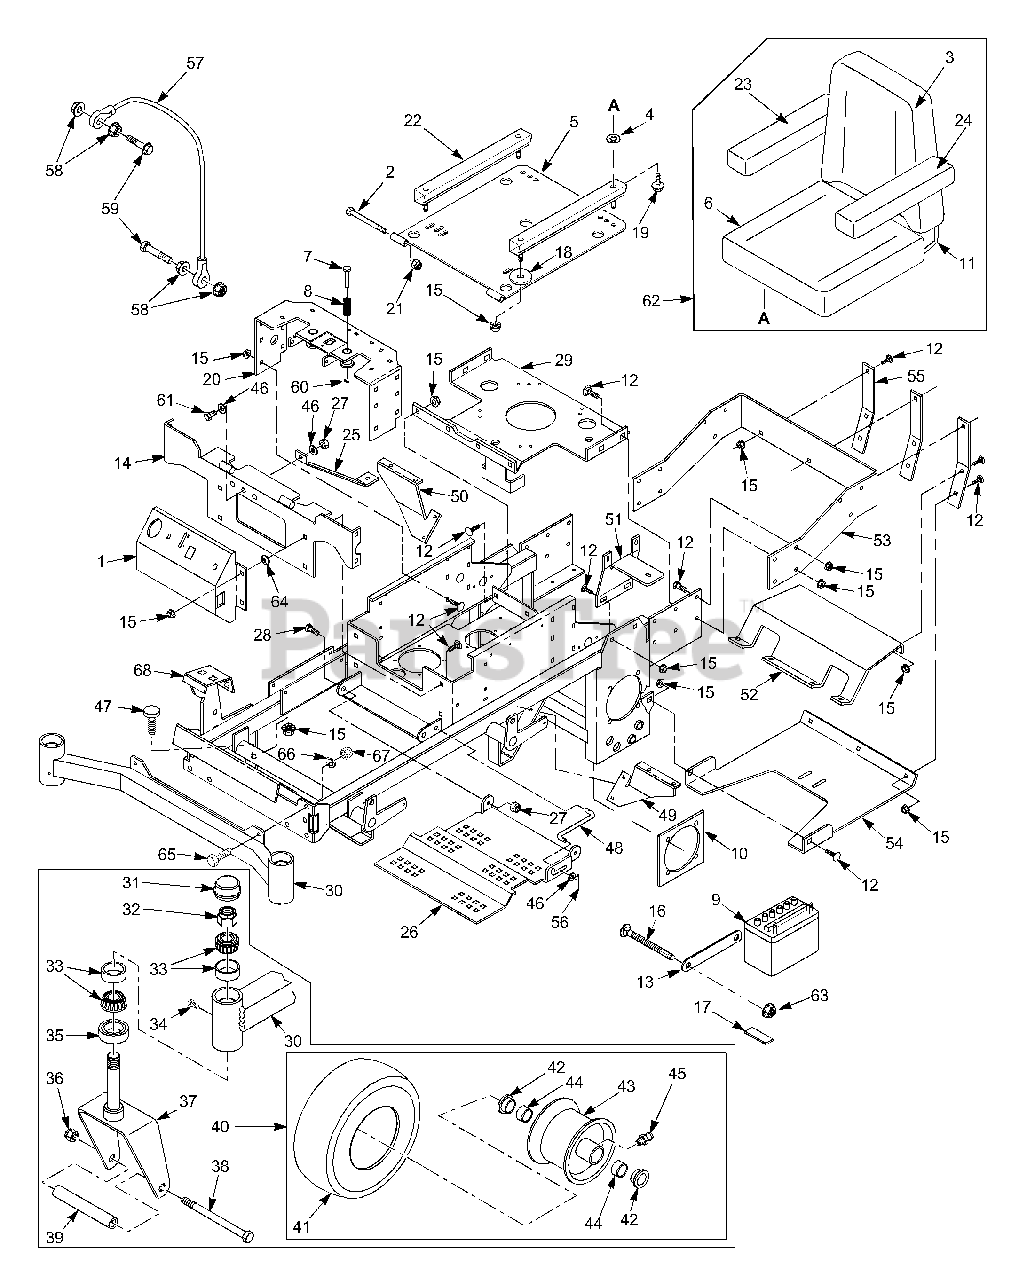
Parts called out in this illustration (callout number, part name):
1	Panel, Instrument
2	Bolt, Hex Head 5/16-18 x 3-1/2"
3	Cushion, Back
4	Flatwasher, 3/8-.406 x 1.5 x .179
5	Plate, Seat Mounting
6	Cushion, Lower Seat
7	Pin Retainer, Spring
8	Spring
9	Battery
10	Plate, Wheel Motor Mounting
11	Pan, Seat Mounting
12	Bolt, Carr. 5/16-18 x 3/4"
13	Plate, Battery Mounting
14	Weldment, Seat Plate Mounting
15	Nut, Serr. Flange 5/16-18
16	Bolt, Carr. 1/4-20 x 6"
17	Pad, Rubber
18	3/8 Flatwasher, 1-1/2" x 7 ga.
19	Bolt, Carr. 5/16-18 x 1"
20	Weldment, Seat Brace
21	Nut, Elastic Stop 5/16-18
22	Seat Track Assy
23	Arm Pad, RH
24	Arm Pad, LH
25	Brace, Seat Plate
26	Footplate
27	Nut, Elastic Stop 3/8-16
28	Bolt, Hex Head 3/8-16 x 1"
29	Plate, Engine Mounting
30	Weldment, Caster Support
31	Cap, Grease
32	Nut, Elastic Stop 1.0-14
33	Bearing Set
34	Plug, 1/4-28
35	Seal, 2.0" OD x 1.625" ID
36	Nut, Elastic Stop 1/2-13
37	Yoke, Front Caster Wheel
38	Bolt, Hex Head 1/2-13 x 7-1/2"
39	Sleeve
40	Caster Wheel Assembly
41	Tire, 13 x 5.0-6 Smooth
42	Bushing
43	Rim
44	Bearing
45	Fitting, Grease
46	Flatwasher, 3/8-.391 x .938 x.105
47	Stud, Rubber Stop
48	Rod, Footplate Prop
49	Bracket, Lower LH Fuel Tank
50	Bracket, Fuel Tank Front
51	Bracket, Fuel Tank Rear
52	Heatshield
53	Bumper, Rear
54	Plate, Skid
55	Bracket, Support
56	Hair Pin Cotter, .080 x 1.19
57	Cable, Seat Stop
58	Nut, Serr. Flange 1/4-20
59	Bolt, Hex Head 1/4-20 x 1-1/4"
60	Roll Pin, Spring 5/32 x 3/4"
61	Bolt, Hex Head 3/8-16 x 1-1/4"
62	Seat Assembly w/Adjuster Rails
63	Nut, Elastic Stop 1/4-20
64	Push Nut, 5/16
65	Bolt, Hex Head 7/16-14 x 1-1/4"
66	Lockwasher, 7/16"
67	Nut, Elastic Stop 7/16-14
68	Main Frame Assembly w/decals
